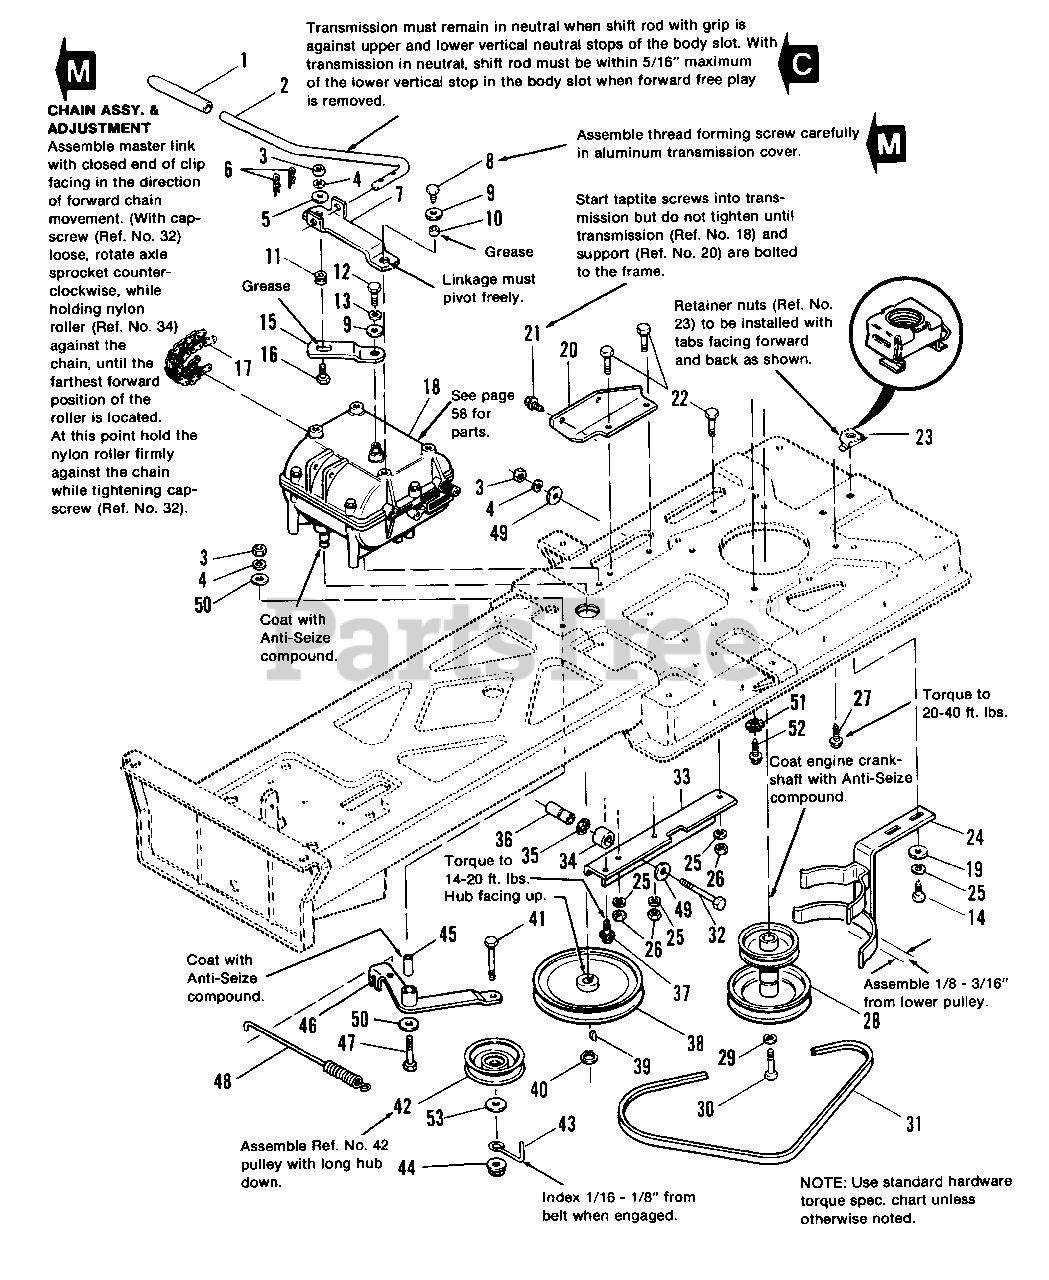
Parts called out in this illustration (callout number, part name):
1	GRIP, Handle
2	ROD, Shift
3	NUT, Hex, 3/8-16
4	LOCKWASHER, 3/8
5	WASHER, Plain, 13/32
6	CUP, Hairpin
7	PIVOT, Shift
8	SCREW, Hex, Taptite 5/16-18 x 3/4
9	WASHER, Plain, 1/4
12	CAPSCREW, Hex, 1/4-28 x 5/8
13	LOCKWASHER, 1/4
14	CAPSCREW, Hex 5/16-18 x 1
15	LINK, Shift
16	CAPSCREW, Hex, 3/8-16 x 1
17	CHAIN, Roller
19	WASHER, Plain, 5/16 (1691535, 1691537, 1691551 only)
20	SUPPORT, Transmission
21	SCREW, Hex, Taptite,1/4-20 x 5/8 (Zinc Plt.)
22	CAPSCREW, Hex, 5/16-18 x 3/4
23	NUT, Retainer, 5/16-18
24	BELT STOP ASSY.
25	LOCKWASHER, 5/16
26	NUT, Hex, 5/16-18
27	SCREW, Hex, Taptite, 3/8-16 x 1-1/4 (Mfg. No.1691106,1691108)
27	SCREW, Hex, Taptite, 3/8-16 x 1-1/2 (Mfg. No.1691535,1691537, 1691551)
28	ENGINE PULLEY ASSY.
29	LOCKWASHER, 7/16
30	CAPSCREW, 7/16-20 x 1-1/2
32	CAPSCREW, Hex, 3/8-16 x 3
33	SUPPORT, Chain
35	E-RING, Retainer
36	SPACER, Roller
37	SCREW, Hex, Whizlock, 5/16-18 x 3/4
38	PULLEY ASSY.
39	KEY, Woodruff, #9
40	RING, Retaining
41	CAPSCREW, Hex, 3/8-16 x 1-3/4
42	PULLEY, Idler
44	LOCKWASHER, Hex, Flange, 3/8-16
46	CLUTCH ARM ASSY.
47	CAPSCREW, Hex, 3/8-16 x 2
49	WASHER, Plain, 13/32 x 1 x 10 Ga.
50	WASHER, Plain, 3/8
51	LOCKWASHER, EXT. Tooth (Zinc Plt.) (1691106, 1691108 only)
52	SCREW, Taptite 3/8-16 x 1-1/2 (zinc Plt.) (1691106, 1691108 only)
53	WASHER, 3/8 (Qty. 1 on Mfg. No. 1691535, 1691537, 1691551)
